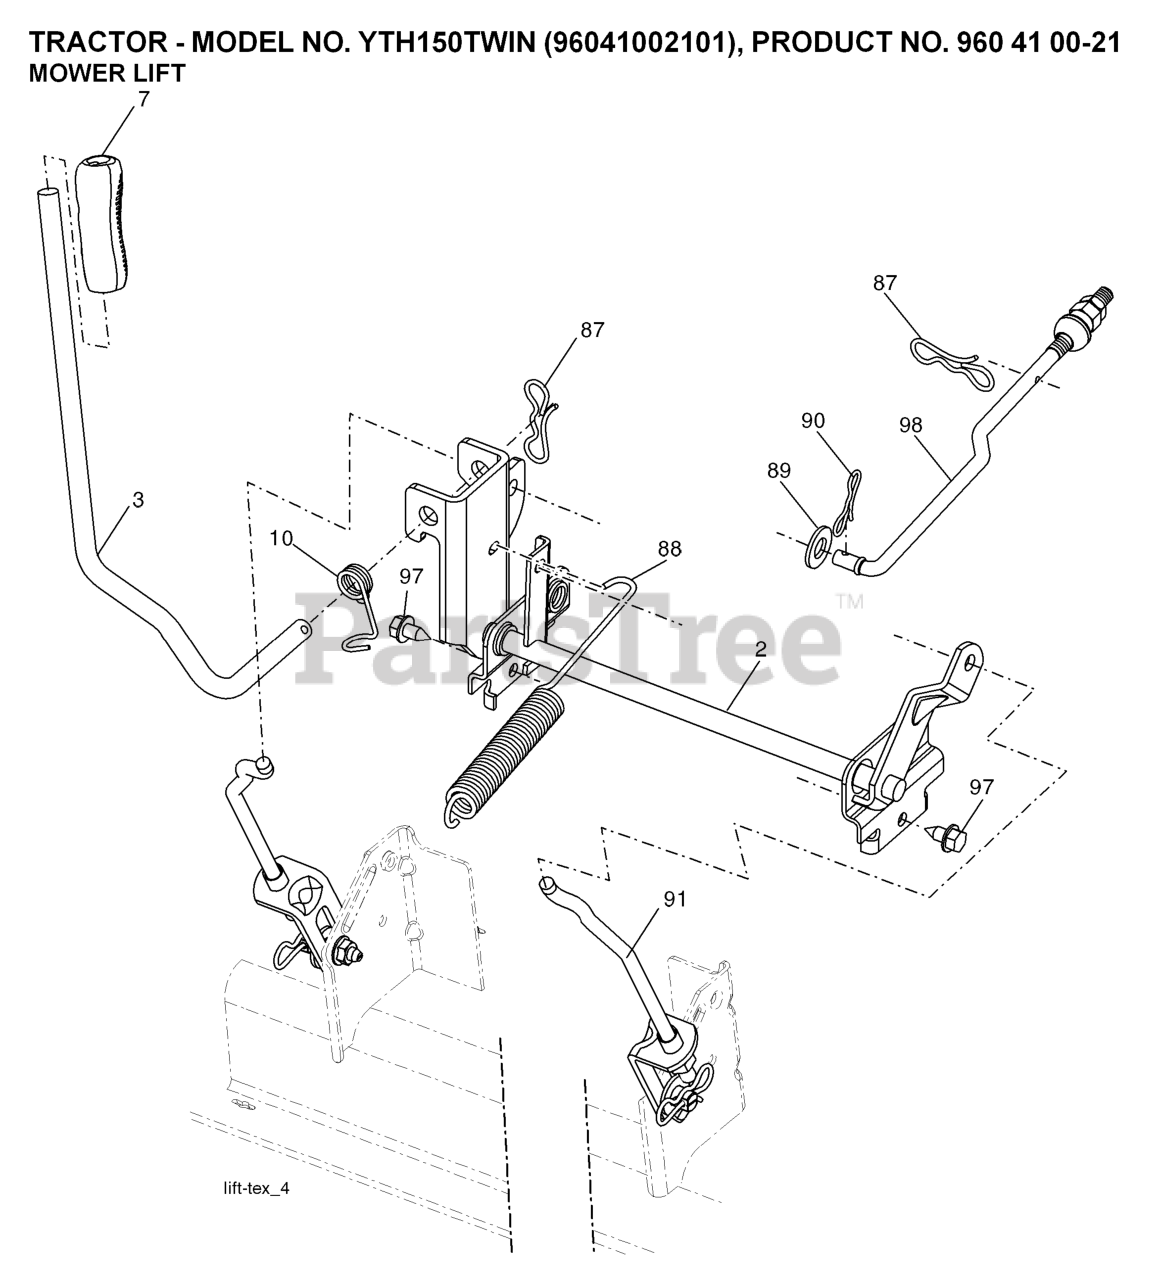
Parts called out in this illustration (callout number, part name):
2	SHAFT.ASM.LIFT.CROSS.H
3	LEVER.LIFT.HANDLE.GT
7	GRIP.LEVER.5625.ID
10	SPRING.TORSION.LIFT.HANDLE
87	PIN.COTTER.7/16.BOW TI.
88	SPRING.LIFT.ASSIST
89	WASHER.CLEAR.ZINC
90	PIN.COTTER.5/16.BOW TI
91	LINK.ASM.LIFT.REAR
97	SCREW, 3/8-16X3/4
98	LINK.ASM.SUSP.FRONT.MW
